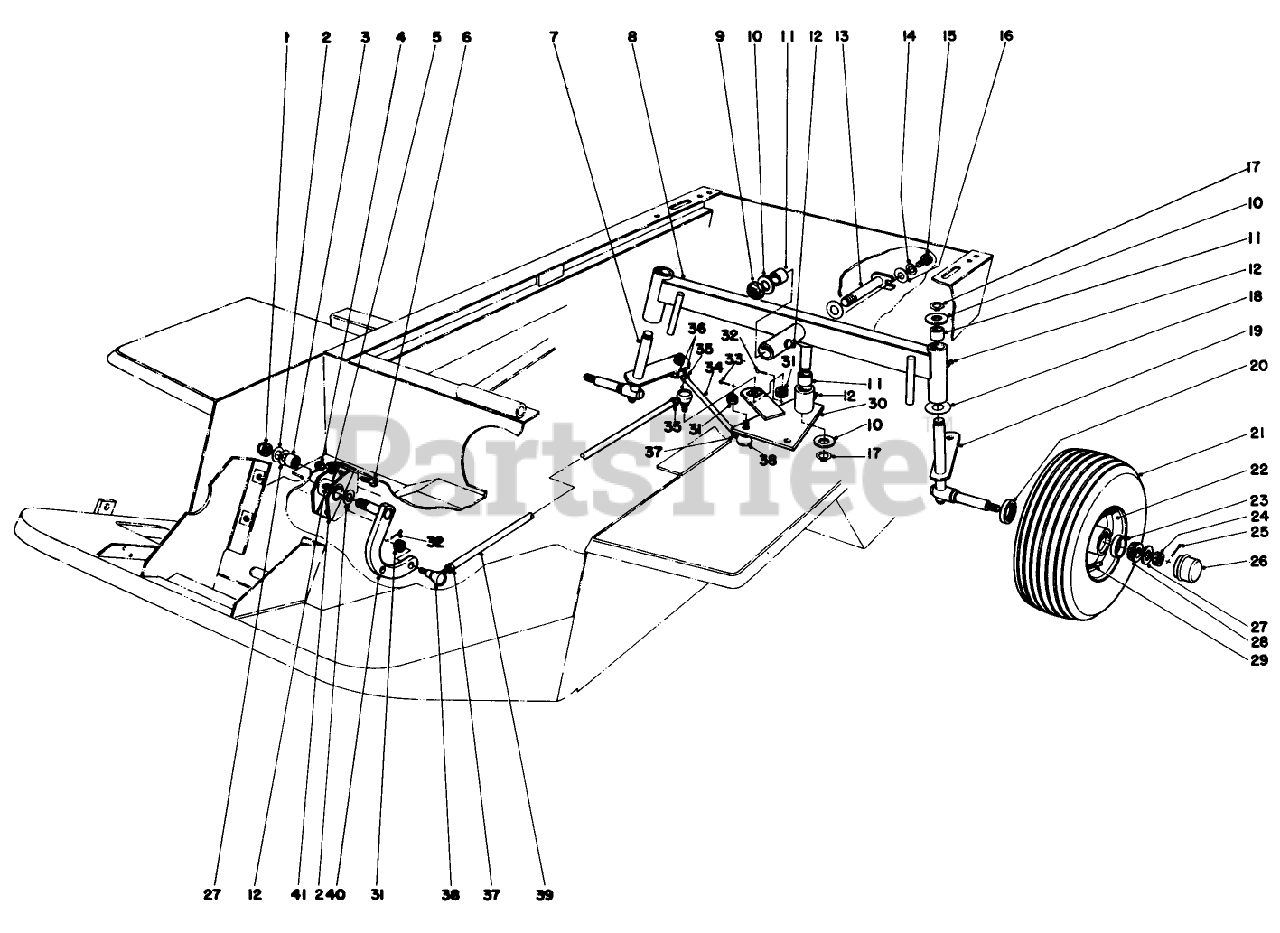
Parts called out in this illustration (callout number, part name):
1	NUT-LOCK, NI
2	THRUST WASHER
3	BEARING-NEEDLE
4	NUT-HEX
5	WASHER-LOCK
6	SCREW-HH
8	REAR AXLE WA
9	NUT-LOCK, NI
12	FITTING-GREASE
14	SCREW-HH
15	SCREW-HH
16	WASHER-FLAT
17	RING-RETAINING
18	WASHER-THRUST
23	BEARING-CUP, TAPERED
24	NUT-HEX, SLOTTED
25	PIN-COTTER
26	CAP-DUST
27	WASHER-FLAT
28	BEARING-CONE, TAPERED
31	NUT-HEX,SLOTTED
33	SCREW-HH
35	NUT-HEX JAM LH
37	NUT-JAM
39	REAR STRG TUBE *PP
40	PIVOT ARM WA
